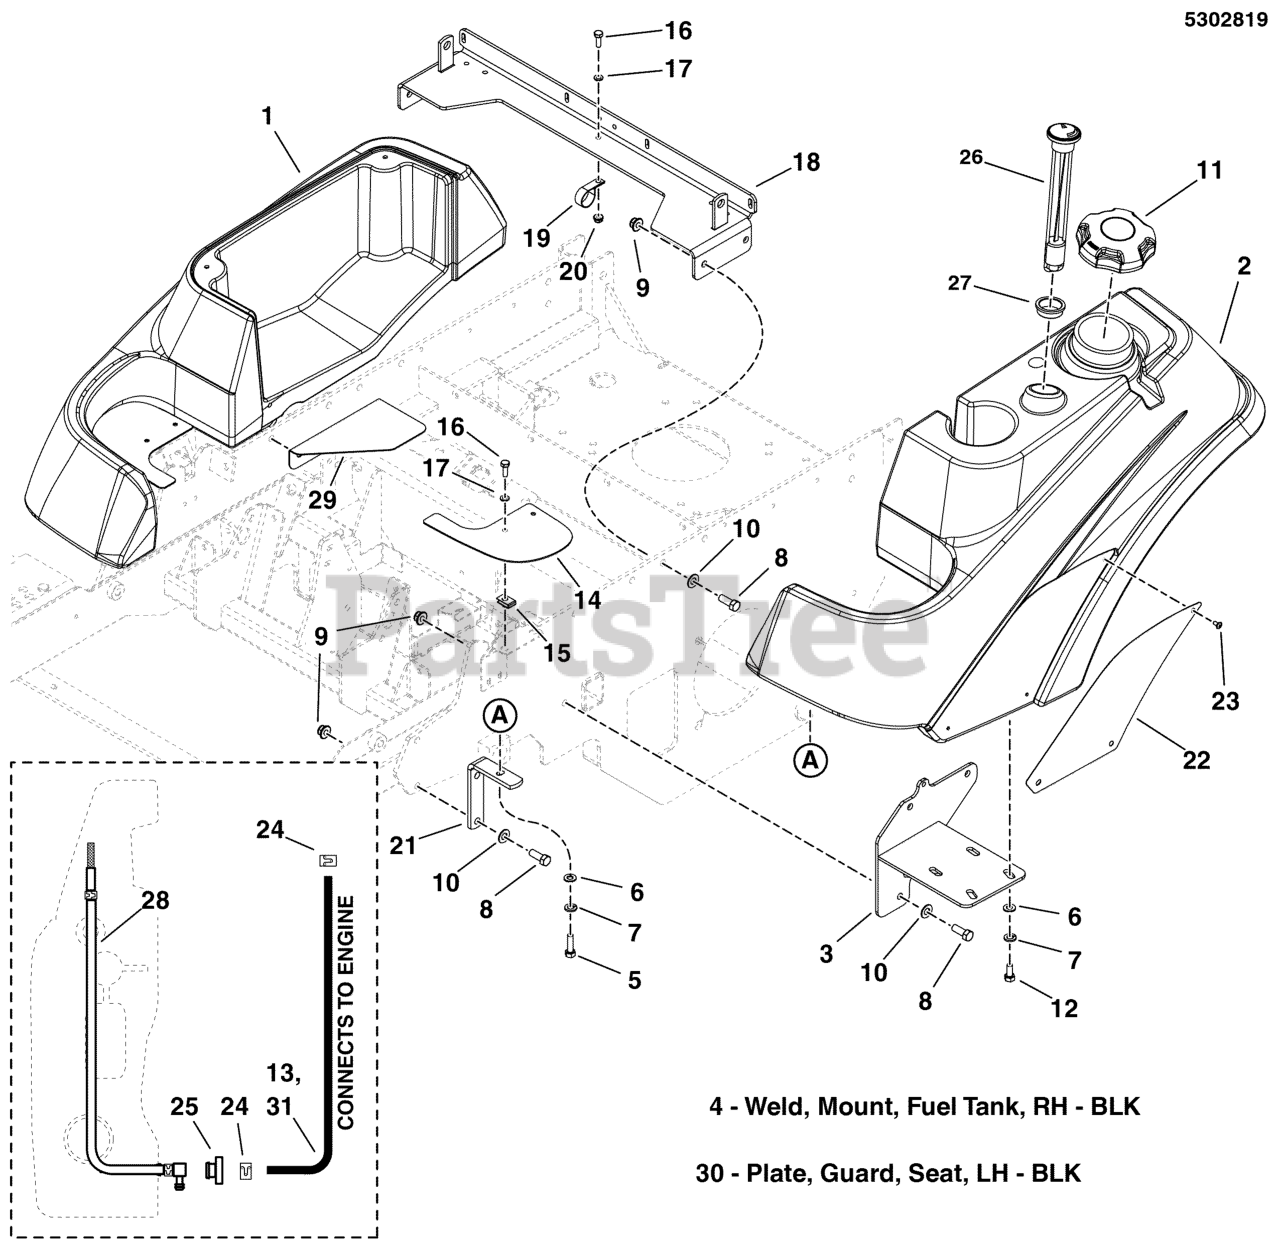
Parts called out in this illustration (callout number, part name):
1	TANK, FENDER, 1500Z - RH
2	TANK, FUEL, LH, 1500Z
3	WELD, MOUNT, FUEL TANK, LH - BLK
5	BOLT, 5/16-18 X 1 GD5 YZ
6	WASHER, 5/16" SAE
7	WASHER, 5/16 LOCK CZ
8	BOLT, 3/8-16 X 1" GD5 CZ
9	NUT, 3/8-16 HEX NYLOCK FLANGE
10	WASHER, 3/8 SAE
11	FUEL CAP, 3-1/2", MANAGED VENT OUT, 12"
12	BOLT, 5/16-18 X 3/4 GD5
13	HOSE, 1/4" FUEL, 4.50"
14	GUARD, MASSEY TANK, 3000 - BLK
15	BODY CLIP, 1/4-20 X 1/2 DEEP
16	BOLT, 1/4-20 X 3/4 GD5 YZ
17	WASHER, 1/4 SAE
18	WELD, MOUNT, HYDRO TANK - RED
19	CLAMP, VINYL INSULATED
20	NUT, 1/4-20 HEX NYLOCK FLANGE
21	BAR, TANK MOUNT, FRONT - BLK
22	PLATE, BADGE - IS1500
23	SCREW, #10-24 X 3/8 ALLEN BHBZ
24	CLAMP, HOSE, EXTERNAL, 1/2 - RED
25	BUSHING-FUEL TANK RED RUBBER
26	GAUGE, FUEL, 12
27	GROMMET, FUEL GAUGE
28	PICKUP TUBE ASM, FUEL TANK
29	PLATE, GUARD, SEAT, RH - BLK
31	HOSE, 1/4" FUEL, 30"
